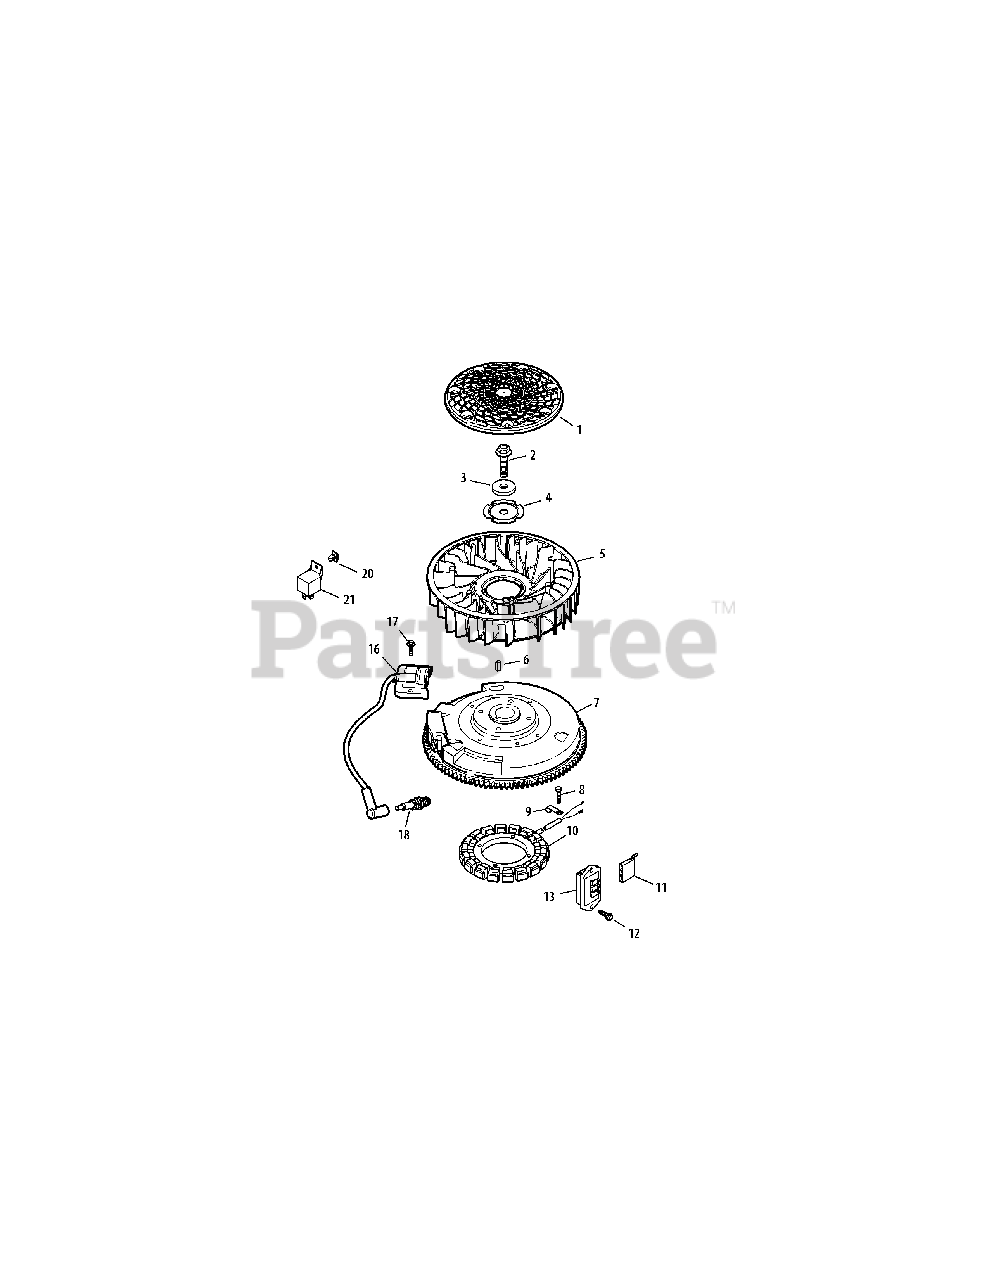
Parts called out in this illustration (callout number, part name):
2	Hex Flange Screw
4	Fan Mounting Plate
6	Straight Flywheel Key
7	Flywheel
8	Thd. Frm. Screw, M5 X 0.8 X 25
10	15 Amp Stator Kit (Inc. KH-25-452-01-S)
12	Flg. Thd. Frm. Screw, M5 X .8 X 20
13	Regulator/Rectifier
16	Ignition Module (CDI Fixed)
17	Flg. Thd. Frm., M5 X .8 X 20
18	Spark Plug (Std)
20	Not used in this application
21	Not used in this application
